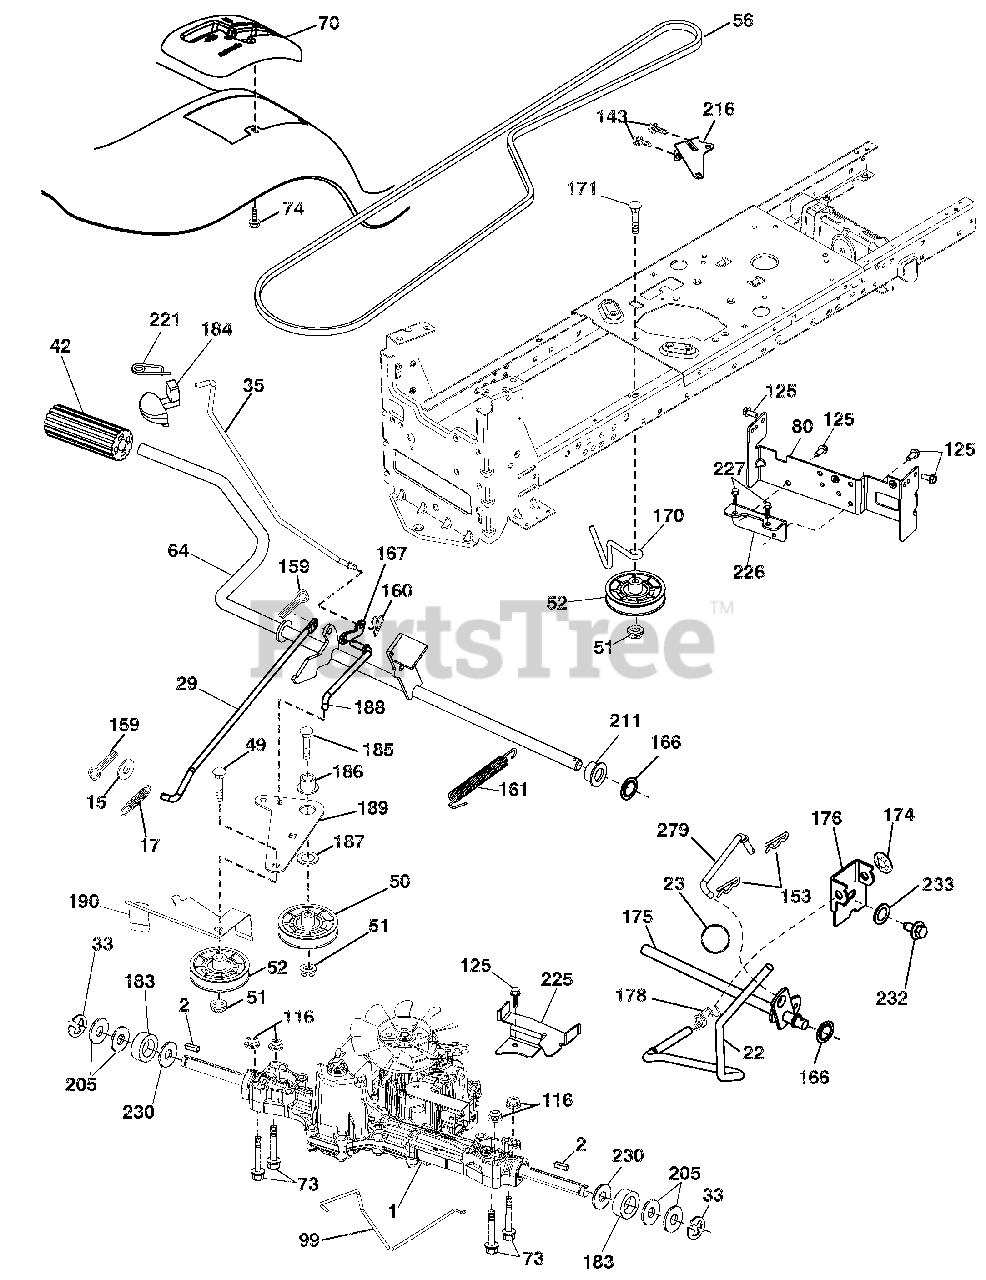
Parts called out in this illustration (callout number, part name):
1	TRANSAXLE, TUFFTORQ K46BA (448348)(ORDER PARTS FROM TRANSAXLE MANUFACTURER.)
2	KEY.SQUARE.2.0 X .1845/.1865
15	WASHER.13/32 X 13/16 X 16 GA.
17	SPRING.BRAKE.K46.GREEN
22	ROD.SHIFT.FENDER.TLT.2006
29	ROD.BRAKE.K46
33	E-RING.#5133-75
35	ROD, BRAKE, PARK
42	COVER PEDAL BLK ROUND
49	BOLT.RDHD.3/8-16UNCX1-3/4.GR5
50	IDLER.FLAT.910"OFFSET
51	Nut, Hex, Flangelock 3/8-16
52	IDLER.V-GROOVE.910"OFFSET
56	V-BELT.MOWER.92.40.42/K46
64	SHAFT ASM.PEDAL.BRAKE CONTROL
70	CONSOLE SHIFT STL HYD BLACK TX
73	BOLT 5/16-18 X 2 1/2 G.5
74	SCREW.HEX.WSH.HI-LO.1/4X1/2UNC
80	STRAP.TORQUE.K46/18"TEX
99	ROD.SPRING.BYPASS.K46.LT.Z
116	Nut, Lock Hex Flange 5/16-18 u
125	SCREW.5/16-18X3/4.SMGML.TAP/BL
143	SCREW.THDROL.5/16-18 X 1/2TYTT
153	RETAINER SPRING
159	PIN.COTTER.1/8 X 3/4.CAD.
160	RETAINER.CLIP(M).DIA.290
161	SPRING.RETURN.CLUTCH.6.75
166	NUT PUSH .625
167	LATCH.BRAKE.PARKING
170	KEEPER BELT CENTERSPAN
171	BOLT.RD.HD.SQ.NK.3/8-16UNC X 2
174	NUT.PUSH..500
175	SHAFT ARM SHIFT
176	ARM.CLEVIS.ROD.SHIFT
178	SPRING.SHIFT.GT.2006
183	SPACER.AXLE.HYDRO/PEERLES
184	HANDLE PARKING BRAKE
185	BOLT.RDHD.3/8-16UNC X2-3/4 GR5
186	SPACER.RETAINER
187	WASHER.13/32 X 2 X 10 GA.
188	LINK.CLUTCH.GROUND DRIVE
189	BELLCRANK.GROUNDRIVE.NSTG/NSTL
190	KEEPER.BELLCRANK.DRIVE.GROUND
205	WASHER.25/32 X 1-5/8 X 16GA.
211	BUSHING.SHAFT.BRAKE.HAND CONTR
216	BRACKET.PULLEY.IDLER.WTEX
221	RETAINER.SPRING.CLIP.HANDLE
225	KEEPER.BELT.TRANSAXLE.K46
226	BRACKET.MOUNT.TORQUE.K46.TLT
227	SCREW 5/16-18 X 3/4
230	WASHER.HARDEN..793 X 1.637X060
232	BOLT.FIN HEX.7/16-14X1 GR5
233	WASHER.SERRATED
279	LINK SHIFT T/A
